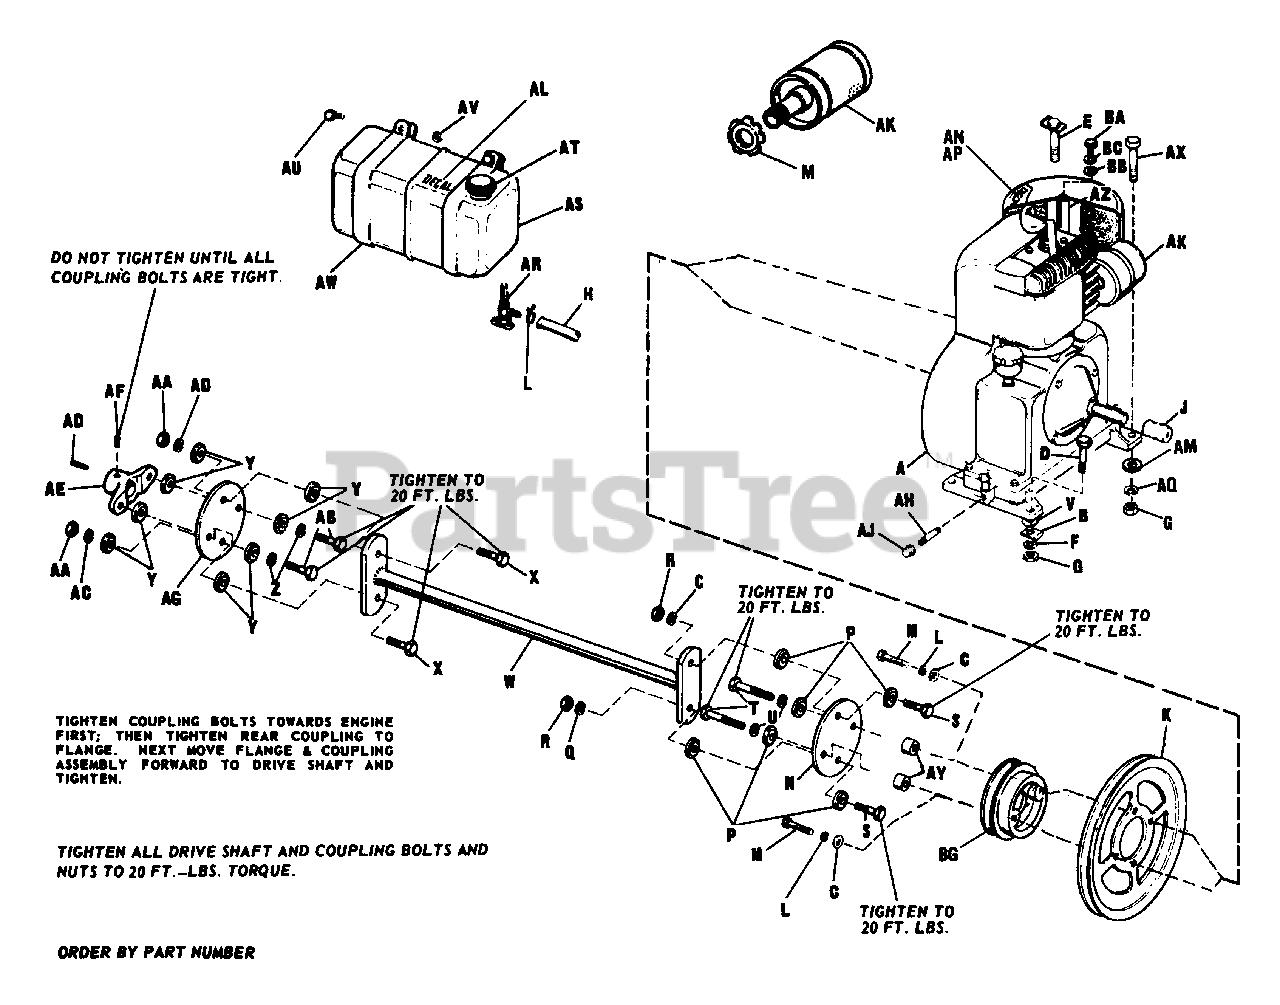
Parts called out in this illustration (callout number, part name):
A	ENGINE, Briggs & Stratton
B	Stop Axle
C	Lock Washer, 3/8"
D	Hex. Cap Screw, 3/8"-16 x 1-3/4" lg.
E	Screw Assembly, Engine, L.H. Rear
F	Lock Washer, 3/8"
G	Full Hex. Nut, 3/8"-16
H	Fuel Hose (Flexible)
J	Crankshaft Extension Guard
K	Engine Pulley
L	Hose Clamp (FOR SERVICE ONLY)
P	Special Washer
Q	Lock Washer, 3/8"
R	Full Hex. Nut, 3/8"-16
S	Hex. Cap Screw, 3/8"-16 x 1-1/4" lg.
T	Hex Capscrew, 3/8-16 x 2-1/2" lg.
U	Lock Washer, 3/8"
V	Plain Washer, 3/8"
W	Drive Shaft Assembly
X	Hex. Cap Screw, 3/8"-16 x 1-1/4" lg.
Y	Special Washer
Z	Lock Washer, 3/8"
AA	Full Hex. Nut, 3/8"-16
AB	Hex. Cap Screw, 3/8"-16 x 1-1/4"
AC	Lock Washer, 3/8"
AE	Drive Shaft Flange
AF	Cup point Socket Head Set Screw, 3/8"-24 x 5/8"
AH	Pipe Nipple. 3/8 x 1" lg.
AJ	Pipe Cap, 3/8"
AK	Exhaust Muffler
AL	Decal, Fuel Tank
AM	Plain Washer, 3/8"
AN	Film, Air Cleaner
AP	Film, Air Cleaner
AQ	Lock Washer, 3/8"
AR	Shut-Off Valve
AS	Fuel Tank
AT	Fuel Tank Cap
AU	Hex. Hd. Capscrew, 1/4"-20 x 1-3/4"
AV	Full Hex. Nut, 1/4"-20
AW	Tank Strap
AX	Hex. Hd. Capscrew, 3/8"-16 x 2" lg.
AZ	Air Cleaner Spacer
BA	Hex. Hd. Capscrew, 1/4"-20 x 5/8"
BB	Plain Washer, 1/4"
BC	Lock Washer, 1/4"
BD	Flywheel Spacer
BE	Drive Hub
